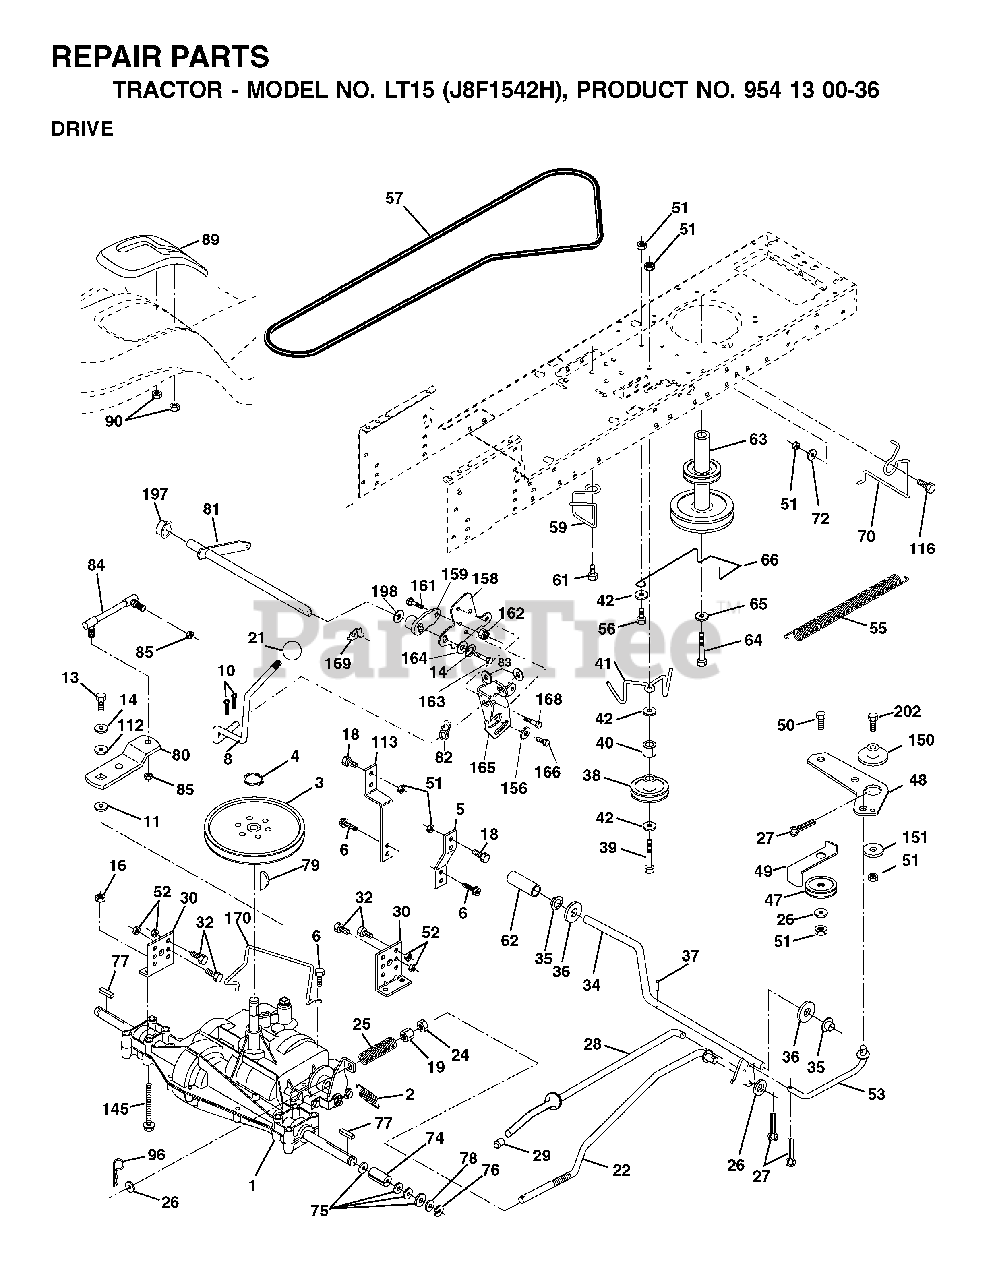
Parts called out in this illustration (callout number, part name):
2	SPRING,BRAKE RETURN
3	PULLEY TRANS
4	RETAINING RING LT
5	STRAP TORQUE
6	SCREW 5/16"
8	ROD SHIFT FENDER ADJUST STLT
10	PIN COTTER
11	WASH-SHFT PLT LT
13	BOLT 1/4-28X3/4
14	LOCKWASHER
16	NUT.71038.31-18.HEX.NYLOCK
19	NUT
21	PISTOL KNOB
22	ROD BRAKE
24	NUT
25	SPRING ROD LT
27	COTTER PIN
28	ROD BRAKE PARK LT
29	PLUNGER CAP
30	BRKT, TRNSXLE MNT 20"
32	BOLT
34	SHAFT, FOOT PEDAL
35	BEARING.NYLON
36	WASHER LT
37	DRIVE PIN
38	FLAT IDLER PULLEY
41	KEEPER.BELT.IDLER.FLAT
42	WASHER
47	IDLER PULLEY
48	BELLCRANK, CLUTCH
49	RETAIN BELT
50	BOLT
51	LOCKNUT
52	LOCKNUT
53	LINK, CLUTCH LT
55	SPRING, RETURN LT
57	V-BELT
59	KEEPER, BELT CENTER
61	SCREW 3/8-16X3/4
62	PEDAL COVER T
63	PULLEY ENGINE
64	BOLT
65	LOCKWASHER
66	KEEPER BELT ENGINE
70	KEEPER BELT ENG
74	SPACER AXLE
76	E-RING LT
77	SQUARE KEY
80	ARM SHIFT
82	SHIFT SPRING
83	WASHER
85	NUT LOCK CENTER 1/4 -28 FNTHD
89	CONSOLE.SHIFT.STLT.6SP.BLACK
96	RETAINER M
112	WASHER LT
113	STRAP TORQUE LH LT
116	BOLT
150	BUSHING.BELLCRANK.GRD.DR
151	WASHER 12/32X2X10GA
156	WASHER.SRRTD.5/16
158	BRACKET
159	HUB
161	BOLT
162	NUT.CROWNLOCK.1/4
165	RP BRACKET
168	BOLT.SHOULDER.5/16-18X
169	PLATE.FASTENING.CROSS.SHAFT
197	NYLINER SNAP 5/8" ID
198	WASHER.NYL.7/8IDX.105"HYD CR
202	BOLT.3/8-16X1.50
204	SCREW 5/16-18X1
